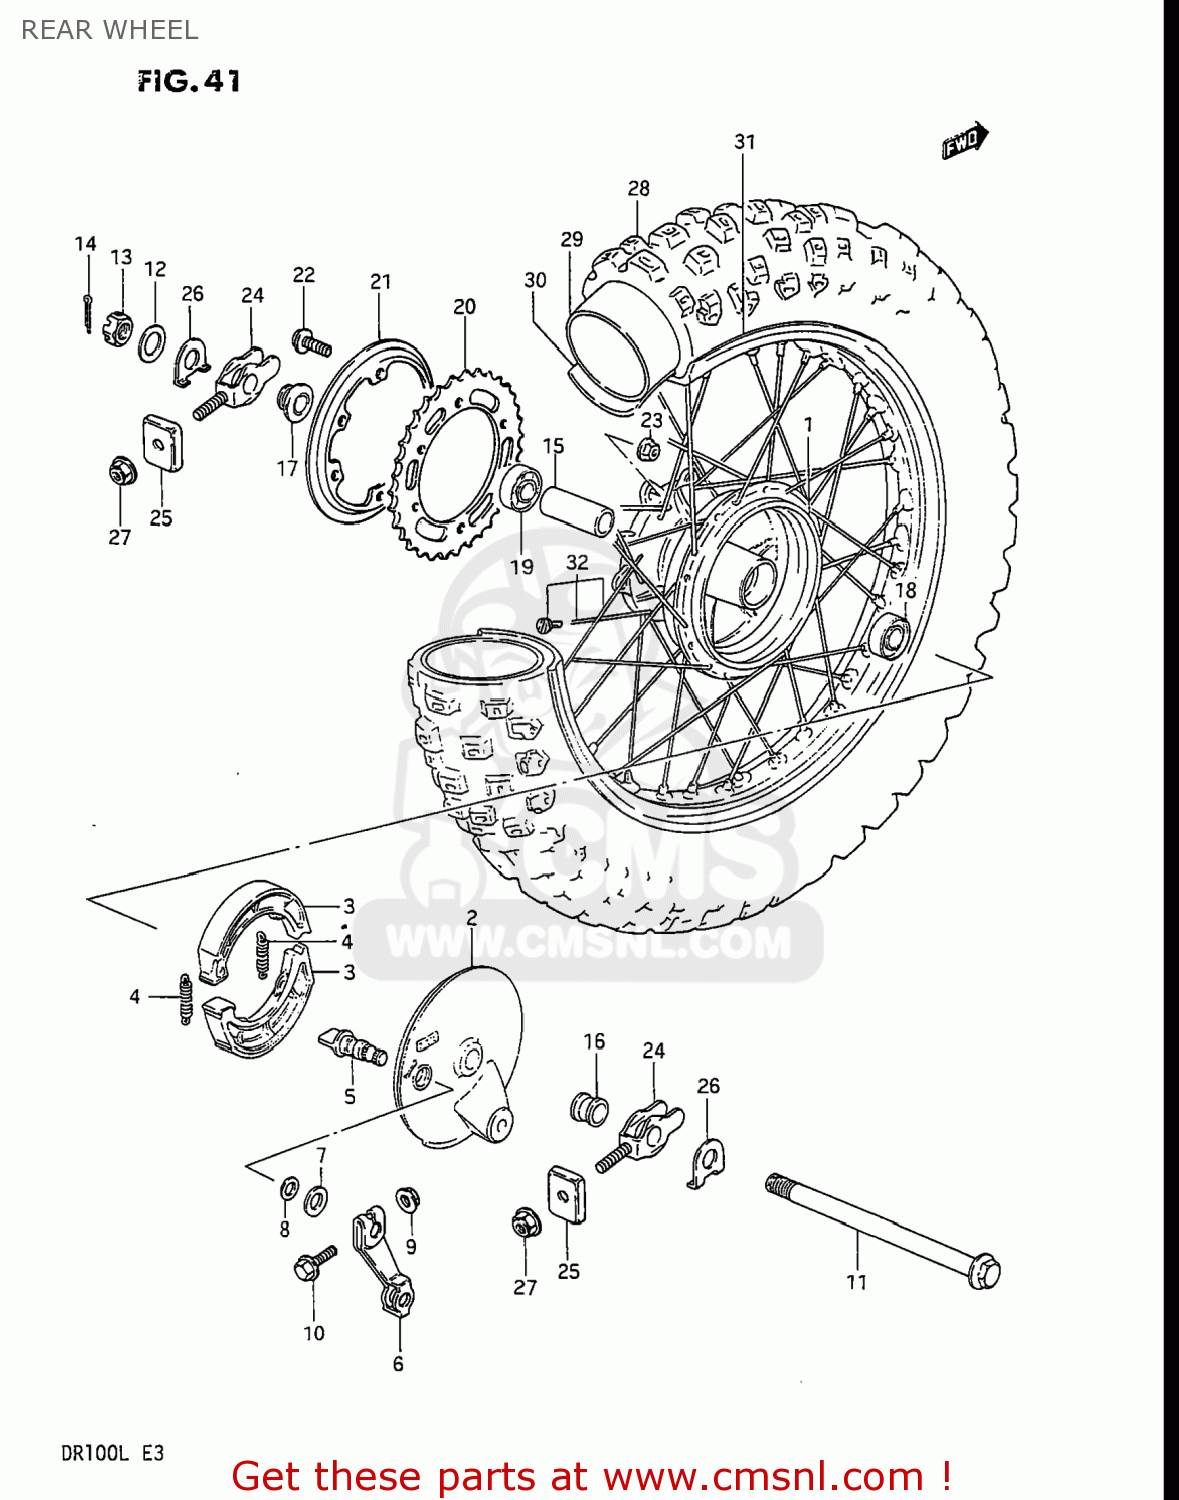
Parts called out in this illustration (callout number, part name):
1	HUB,RR WHEEL
2	PANEL,ANCHOR
3	SHOE,BRAKE
4	SPRING(L:34)
5	CAM,FRONT BRAKE
6	LEVER,RR BRAKE CAM
7	WASHER (14.5X22X1.6)
8	O-RING (D:2.4 ID:13.8)
9	NUT
10	BOLT 6X35
11	AXLE,REAR
12	WASHER
13	NUT
14	COTTER PIN
15	SPACER(15.3X21.7X97)
16	SPACER,REAR AXLE
17	SPACER,RR AXLE,L
18	BEARING
19	BEARING
20	SPROCKET,RR(42T)
21	PLATE,CHAIN SIDE
22	BOLT(8X33)
23	NUT
24	ADJUSTER,CHAIN
25	ADJUSTER,CHAIN
26	WASHER
27	NUT
28	TIRE 4.10-14
29	TUBE ASSEMBLY,WHEEL,INNER
30	PROTECTOR,WHEEL,INNER
31	RIM,REAR WHEEL
32	SPOKE ASSY,RR WHEEL
